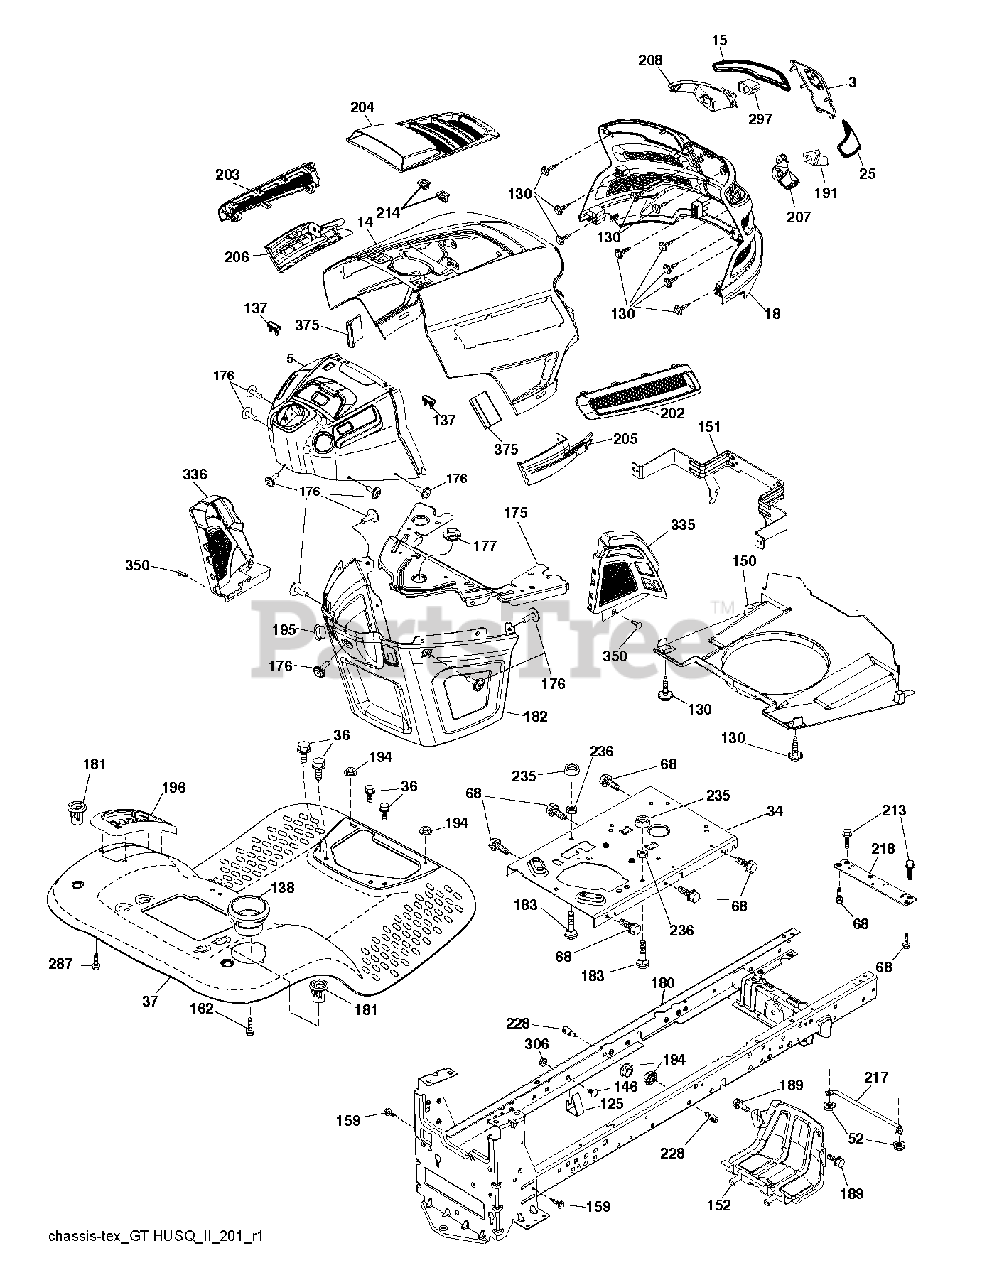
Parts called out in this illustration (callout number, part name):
3	APPLIQUE.SUBASM.GT.HUSQ.II
5	UPPER.GT2.SVC.MINDING.C-O.M;H
14	HOOD.ASM.HUSQVARNA.GT.TEX.ORAN
15	LENS.HEADLIGHT.LH.GTII.2011
18	GRILLE.SUBSTRATE.2011.
25	LENS.HEADLIGHT.RH.GTII.2011
34	PLATE.ENGINE.WELDED.CHASSIS
36	SCREW 5/16"
37	FENDER.TLT.PDL.CNTRL.W/CPH.ORG
52	LOCKNUT
68	SCR 5/16-18 X 1/2 SELFTAP ZN
125	CLIP.FUEL.LINE
130	SCREW.#10 X 0.750.BOS
137	BUMPER DASH
138	HOLDER.CUP.LT.GREY
146	BOLT.RDHD.SHT.SQNK.3/8-16X5/8
150	AIR.DUCT.GTV.BLACK
151	BRACKET.PIVOT.HOOD.GT.HUSQ.II
152	SHIELD.BROWNING.PNT.GT.V2
159	SCREW, 3/8-16X3/4
162	SCREW.HI-LO.CONSOLE
175	Crossmember Plate
176	SCREW.#10-24X5/8.RN.QU
177	BUSHING STEERING
180	CHASSIS
181	BUSHING.MNT.FEND.CRGO.TEX.49
182	DASH.LOWER.COMMON.12V.ADAPTOR
183	BOLT.5/16-18X1-1/4 FULL THD
189	SCREW
191	INSERT.REFLECTIVE.RH.HUSQ.GTII
194	NUT LOCK HEX FLANGE 5/16-18
195	PLUG.HOLE.DASH.LOWER.12V.BLK
196	DECKLFT.CONSOL FULL ASSM GREY
202	VENT.SIDE.RH.GT.HUSQ.II.
203	VENT.SIDE.LH.GT.HUSQ.II.498
204	VENT.TOP.HUSQ.GT2
205	SIDE.TRIM.RH.GT.HUSQ.II
206	SIDE.TRIM.LH.GT.HUSQ.II.GRAY
207	BEZEL LIGHT.RH.GT.II.MYLAR
208	BEZEL LIGHT.LH.GT.II.MYLAR
213	BOLT
214	CLIP.RETAINER.TINNER.
217	ROD.PIVOT.HOOD
218	X-PIECE.HOOD.STOP.NON/
228	STUD.FASTNER.W/ANTI-ROTATE
235	SPACER FENDER
236	NUT.CENTERLOCK.5/16-
287	SCREW 1/4X20
297	INSERT.REFLECTIVE.LH.HUSQ.GTII
306	NUT LOCK FLG 3/8-16 UNC
335	COVER.LOWER.DASH.RH.BLACK
336	COVER-LH.LOWER.DASH.GT2.BLACK
350	CLIP.X-MAS.TREE
375	BUMPER CLIP-ON. DASH 1"
